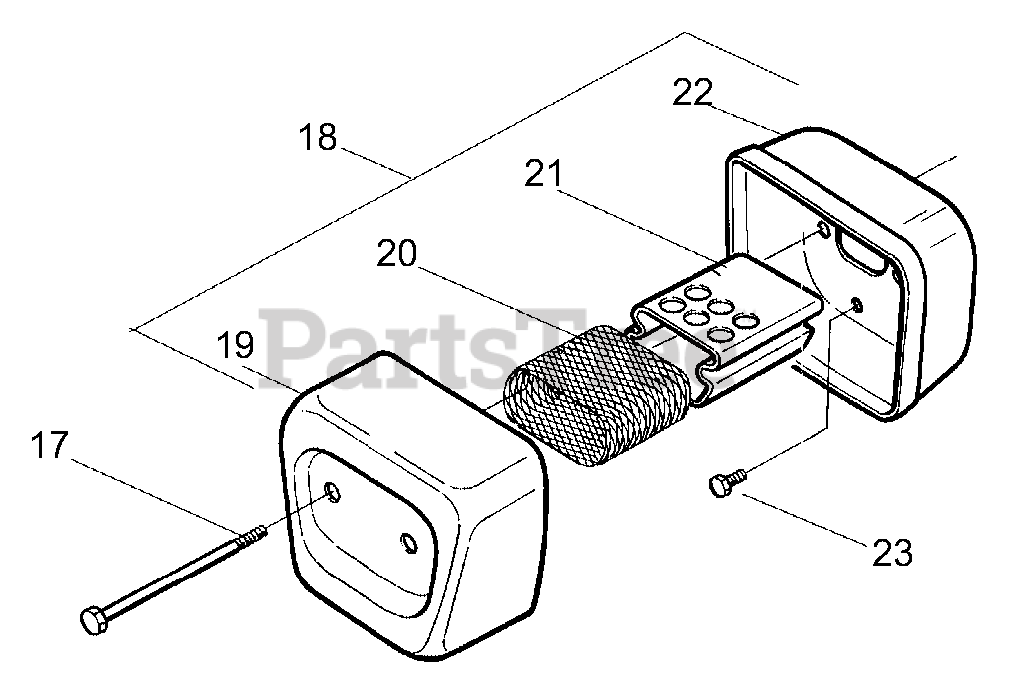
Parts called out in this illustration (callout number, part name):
18	Muffler Kit
19	Muffler Cover
20	Spark Arrestor Screen
21	Muffler Diffuser
22	Muffler Body
23	Muffler Bolt
